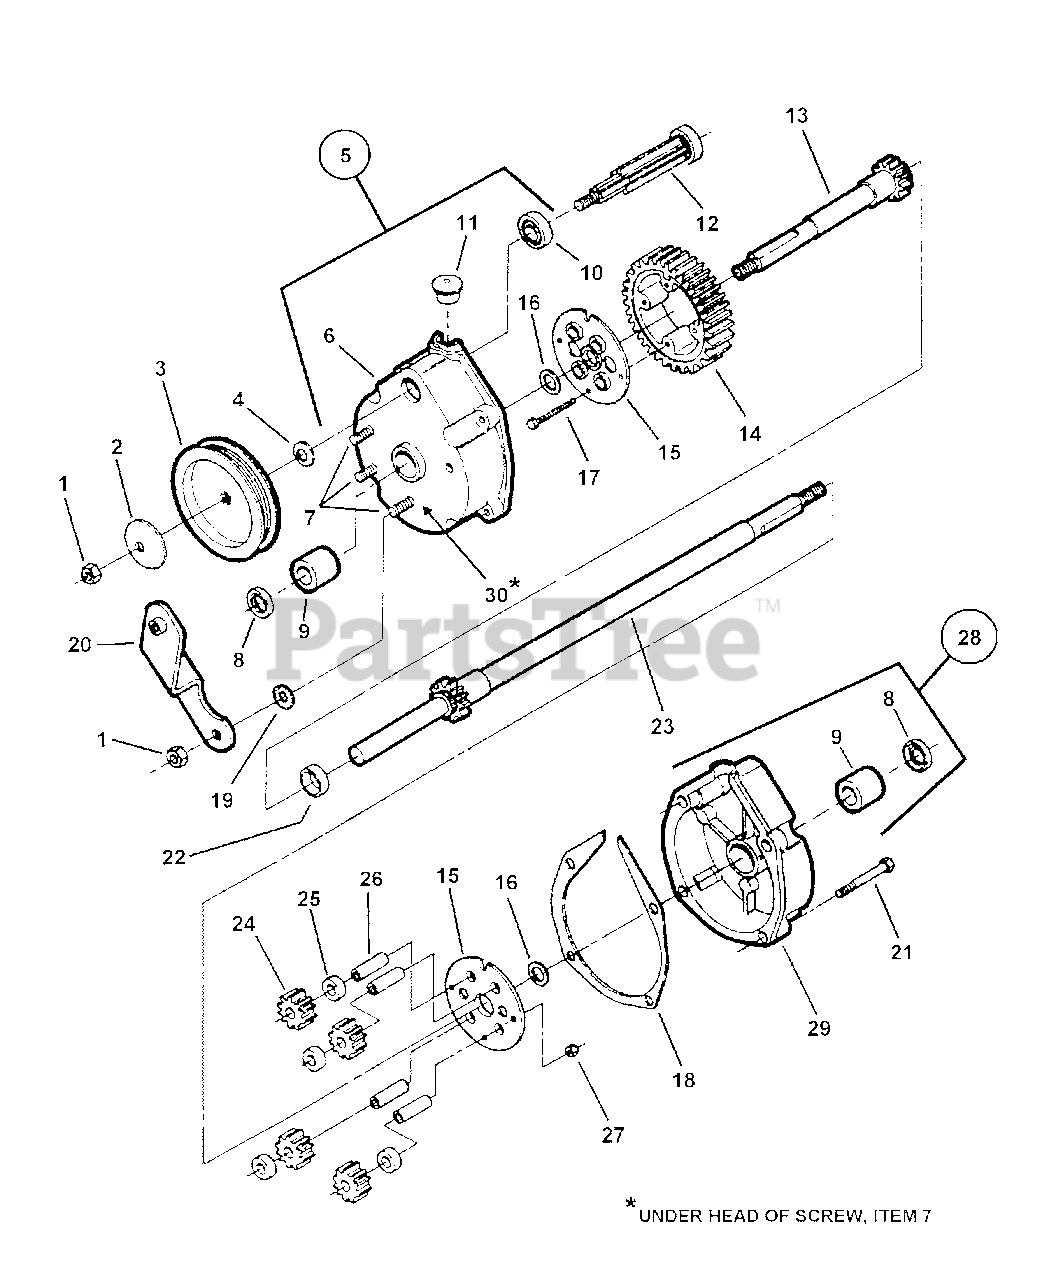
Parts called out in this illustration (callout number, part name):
1	NUT, 5/16-24 Hex Lock
2	WASHER, Cone
3	PULLEY, Poly-V Belt (3.5" O.D.)
4	WASHER, 44 x .78 x .025 Curved
5	ASSEMBLY, Right Housing (Incl. items 6, 7, 8, 9, 10 & 30) (no longer a part sale item)
6	HOUSING, Right Side
7	SCREW, 5/16-24 x 1-1/8" Rib Neck, GR 5
8	SEAL, 5/8" Internal Diameter
9	BEARING, Tapered (Differential Housing)
10	BALL BEARING, 7/16 I.D., 1/1/8" O.D.
11	PLUG, Transmission Housing
12	GEAR, Input
13	AXLE, Short
14	GEAR, Differential (46 Tooth)
15	PLATE, 46T Gear
16	WASHER, Thrust, 3/4" I.D.
17	SCREW, #10-32 x 1-1/2" Hex Head Cap GR 5
18	GASKET, Housing
19	WASHER, 5/16" Internal/External Tooth Lock
20	BRACKET, Differential
21	SCREW, 1/4-20 x 1" Hex washer Self-Tap
22	SPACER, Axle Gear
23	ASSEMBLY, Long Axle
24	GEAR, Pinion (12 tooth)
25	SPACER, Pinion Gear
26	SHAFT, Pinion
27	NUT, #10-32 Hex Nyloc
28	ASSEMBLY, Left Housing
29	HOUSING, Left
30	GASKET, 5/8" O. D.
